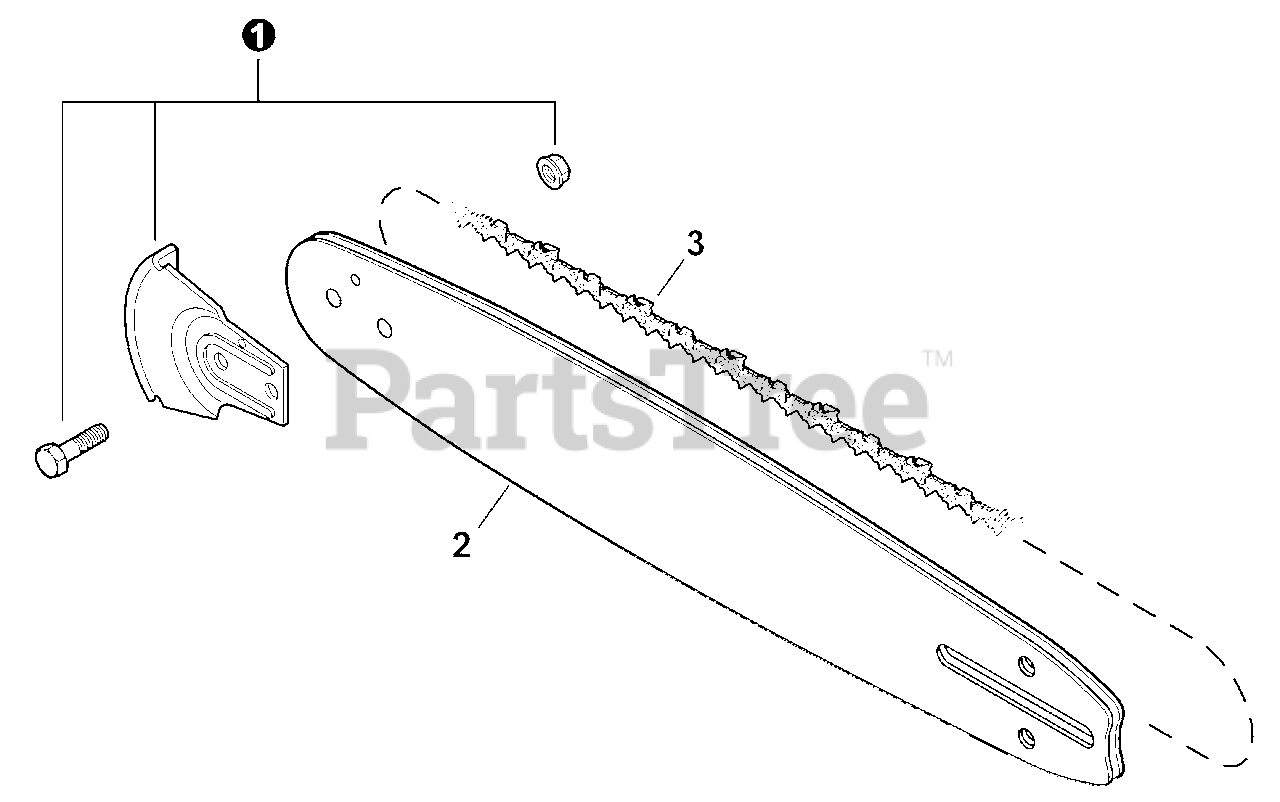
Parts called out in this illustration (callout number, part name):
1	KICK GUARD KIT
2	GUIDE BAR, 14" (.050" Ga)
3	SAW CHAIN 14" (.050" Ga)
